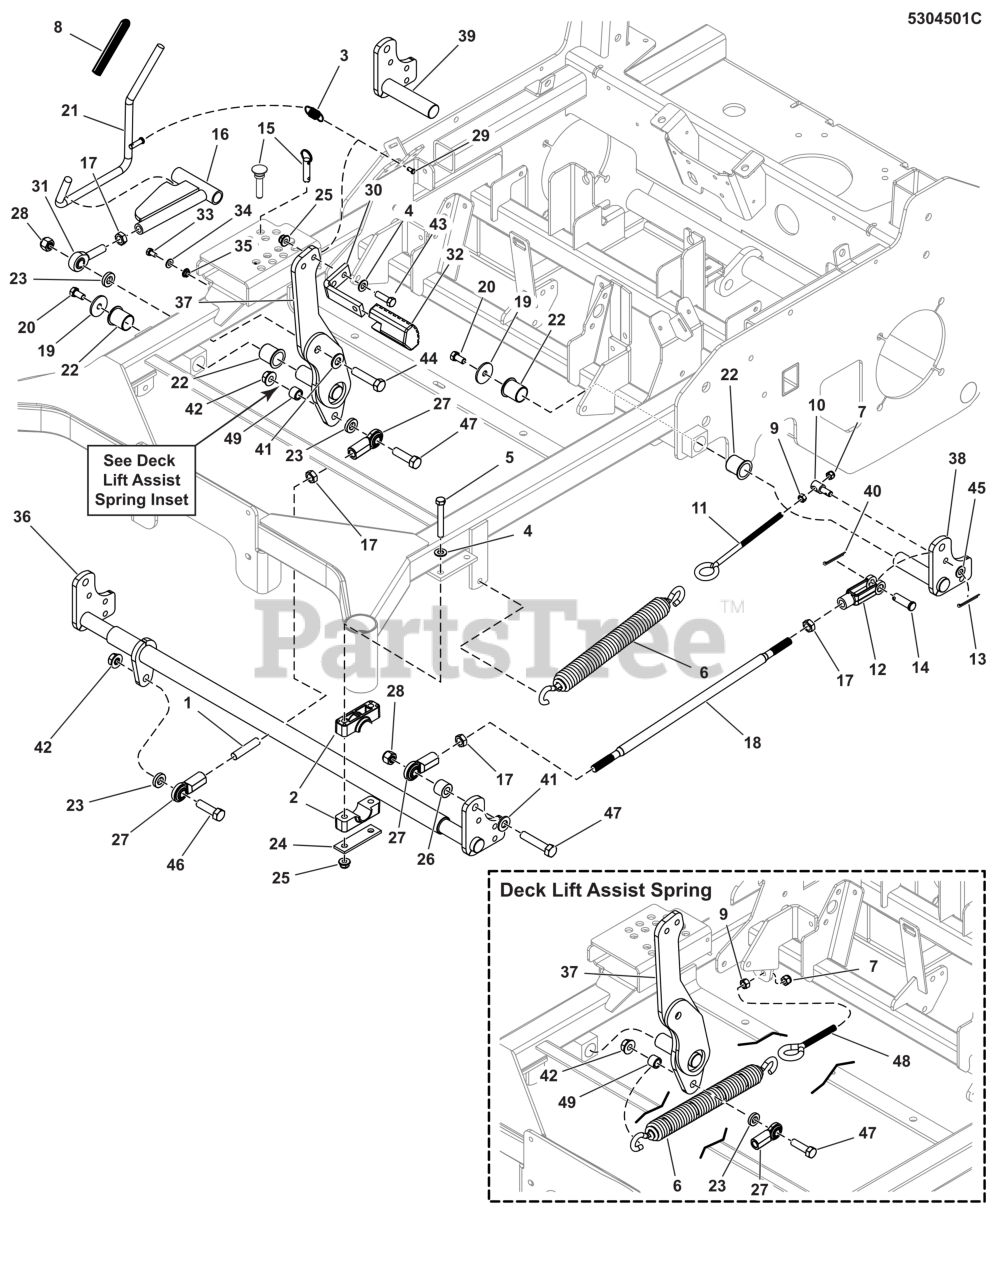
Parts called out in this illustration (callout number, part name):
1	ROD, THREADED, 1/2-20 X 2.25
2	PIVOT BLOCK, PLASTIC
3	SPRING-EXT, .740 ODX2.025LGX.072WR, BLK
4	WASHER, 3/8 SAE
5	BOLT, 3/8-16 X 2-3/4" GD5 CZ
6	SPRING-EXT, 1.393 ODX13.25LGX.218WR, BLK
7	NUT, 3/8-16 HEX NYLON LOCK
8	GRIP, FOAM, .475 X 4.35 X .095
9	NUT, 3/8-16 HEX
10	ADJUSTER, DECK HANGER
11	EYE BOLT, 3/8-16 X 8, 3THRD, 1EYE, CZ
12	CLEVIS, 1/2-20, STEEL, CLEAR ZINC
13	PIN, COTTER, 1/8 X 3/4
14	PIN, CLEVIS, 1/2 X 1-23/64, PLATED
15	PIN, HITCH, 1/2 X 2.0
15	LIFT, Deck
16	WELD, DECK ADJUST LINK - RED
17	NUT, 1/2-20 HEX JAM
18	ROD, DECK LIFT, 19.25, CZ
19	WASHER, .390 X 1.50 X .109, CZ
20	BOLT, 3/8-16 X 3/4, PLT W/PATCH
21	WELD, ROD DECK LIFT, F320Z - BLK
22	BUSHING, 1.00 X 1.13 X 1.38, PLASTIC
23	SPACER, .52 X 1.00 X .22, PM, CZ
24	PLATE, PIVOT BLOCK SUPPORT - BLK
25	NUT, 3/8-16 HEX NYLOCK FLANGE
26	SPACER, .52 X 1.00 X .75, CZ
27	JOINT-BALL .500-20 THD .500ID, CLR ZINC
28	NUT, 1/2-13 HEX NYLON LOCK
29	PIN, CLEVIS, 1/4 X 1/2, PLATED
30	PEDAL, FOOT - BLK
31	BALL JOINT, 1/2-20, MALE
32	PEDAL, Rubber
33	HHCS, 1/4-20 X 0.625, GR5, ZINC/CLEAR
34	WASHER, 1/4 SAE
35	NUT, 1/4-20 HEX SERR. FLANGE
36	WELD, DECK LIFT SHAFT, 200/320 72" - BLK
37	WELD, DECK LIFT PEDAL, F320Z - RED
38	WELD, DECK LIFT LEVER, F320Z, LH - RED
39	WELD, DECK LIFT LEVER, F320Z, RH - RED
40	PIN, COTTER, 1/8 X 1-1/4
41	WASHER, 1/2 SAE
42	NUT, Hex Flange, Nylock, 1/2-13
43	BOLT, 3/8-16 X 1-1/4" GD5 CZ
44	BOLT, 1/2-13 X 2-1/4" GD5 CZ
45	WASHER, 3/8 GD.9 FLAT
46	BOLT, 1/2-13 X 2" GD5 CZ
47	BOLT, 1/2-13 X 2-1/2" GD5 CZ
48	EYE BOLT, 3/8-16 X 5, 2.88THRD, 1EYE, CZ
49	SPACER, .51 X .75 X .56, PM, CZ
